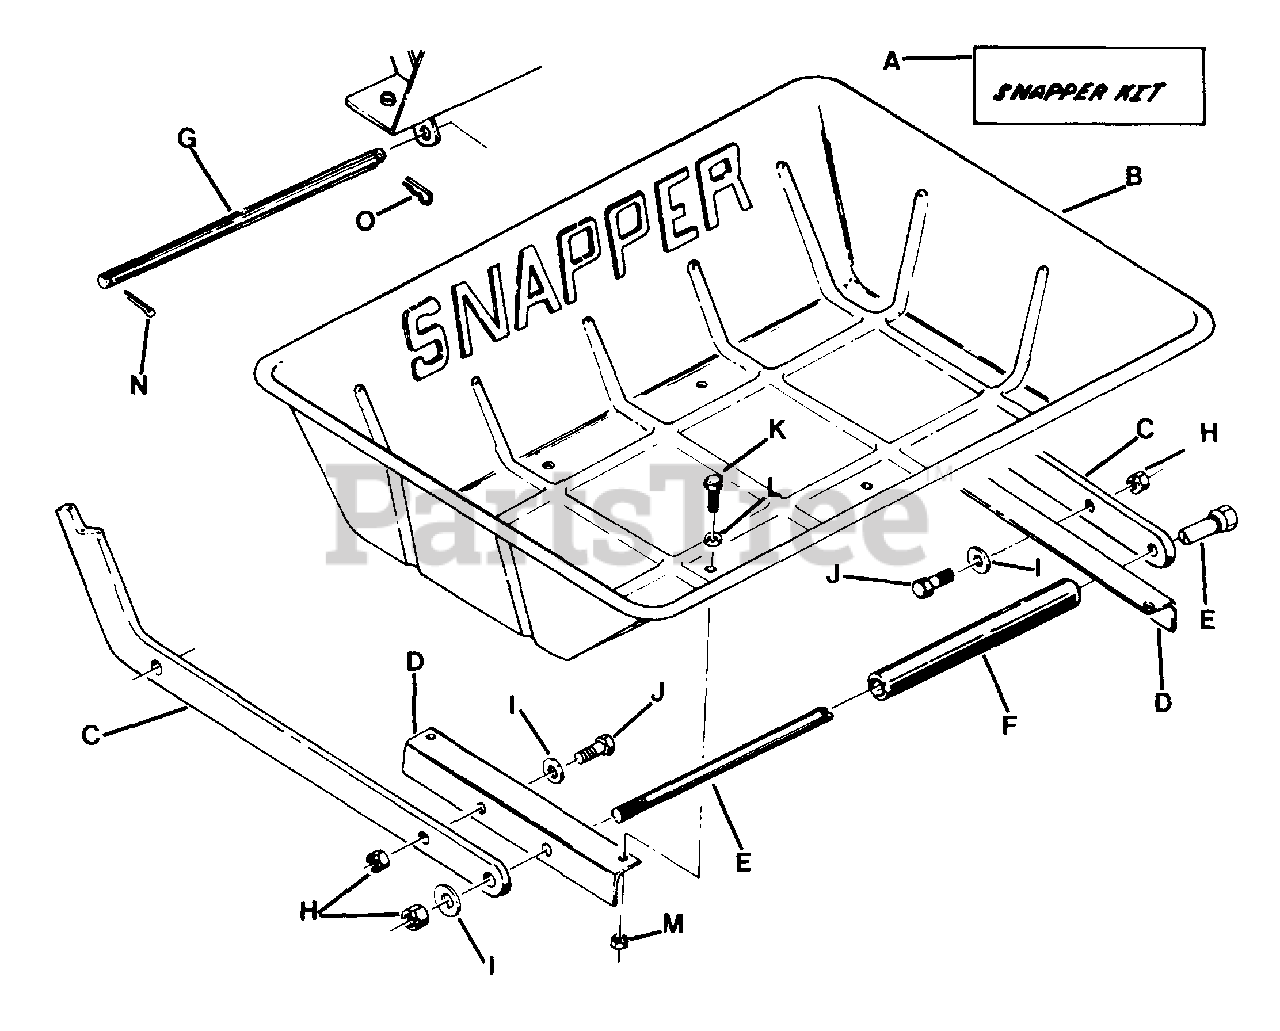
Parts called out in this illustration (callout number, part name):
A	KIT, LOAD CARRIER
B	BOX, TOTE
C	RAIL, SIDE
E	BOLT, 3/8-16 x 10"
F	SPACER, BOX
G	PIN
H	NUT, 3/8-16 HEX LOCK
I	WASHER, 3/8 SAE
J	SCREW, HEX HEAD CAP 3/8-16 x 1
K	SCREW, HEX HEAD CAP 1/4-28 x 3/4 GRADE 5
L	WASHER, 1/4 SAE
M	NUT, 1/4-28 HEX LOCK
N	COTTER-PIN, 5/32 x 1
O	PIN, HAIR
